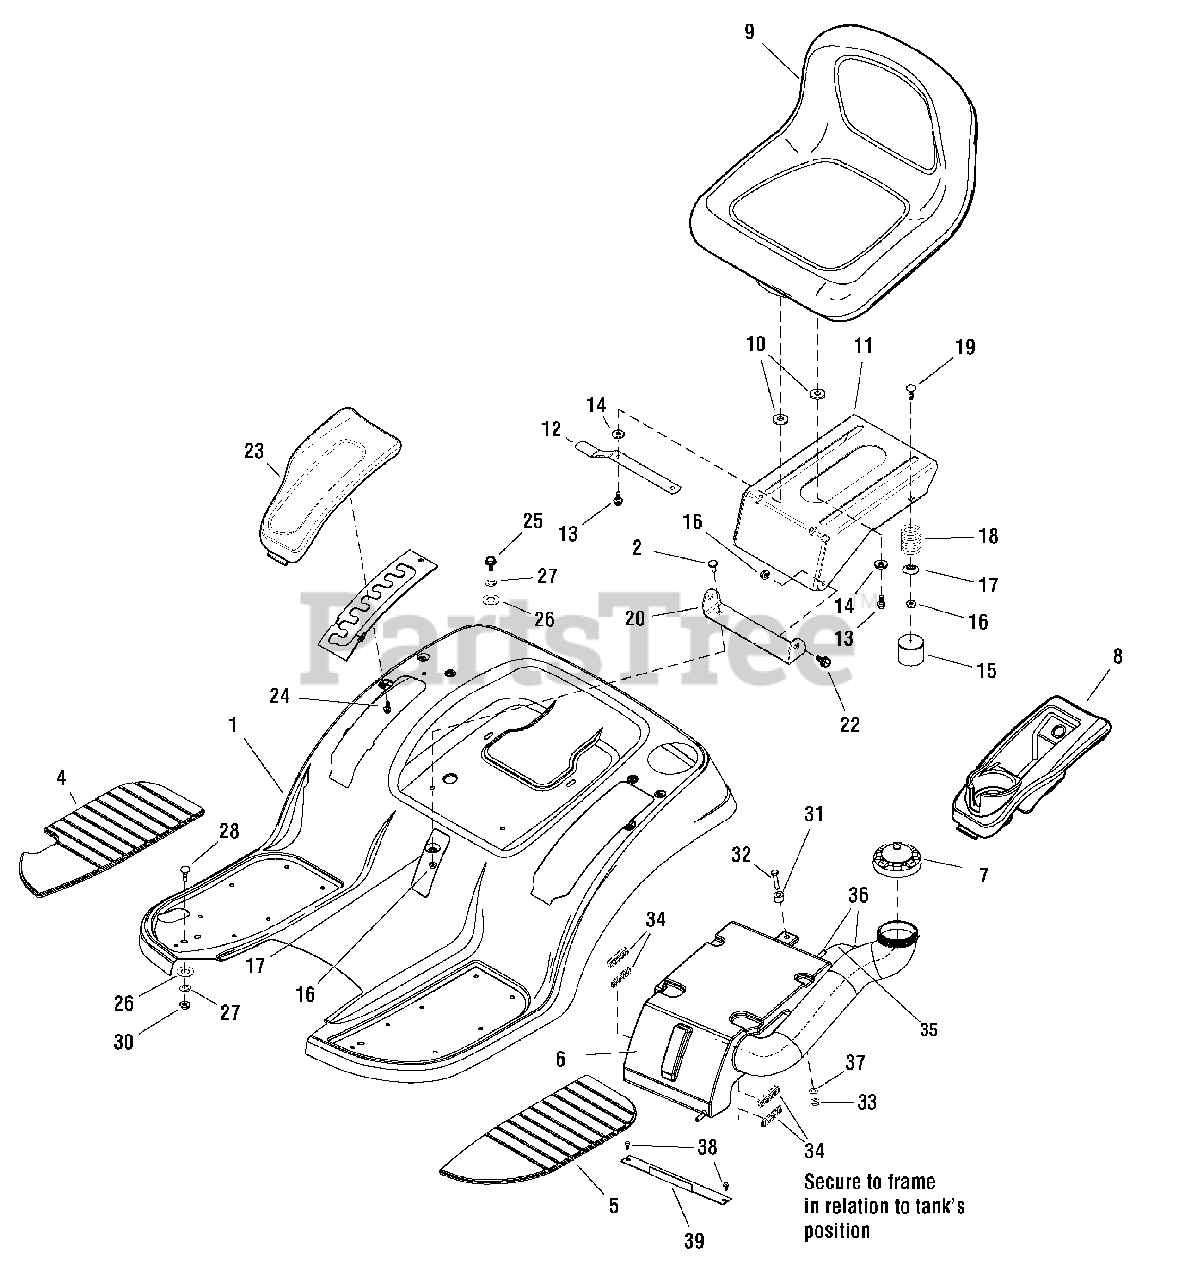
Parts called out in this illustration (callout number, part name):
1	DECK, Seat
2	BOLT, 5/16-18 x 3/4
4	PAD, Footrest, Right
5	PAD, Footrest, Left
6	TANK, Fuel 9-2770-244
7	CAP, Fuel
8	POD, Cup Holder, Left
9	SEAT, High Back
10	SPACER
11	SUPPORT, Seat
12	LATCH, Seat
13	SCREW, Flange 5/16-18 x 1
14	WASHER, 5/16
15	COVER, Spring
16	NUT, Hex Flange 5/16-18
17	WASHER, Spring
18	SPRING, Compression
19	BOLT, Round Head, 5/16-18 x 3/4
20	PIVOT, Seat
22	BOLT, Shoulder, 5/16-18 x 1/8
23	POD, Lift, Right
24	SCREW, Hex, 1/4-1/2
25	BOLT, M8 x 16
26	WASHER, 8.4
27	WASHER, 8
28	BOLT, M8 x 20
30	NUT, M8
31	DISTANCE, Lift 0-9521-289
32	BOLT, M6 x 30
33	NUT, M6
34	BRAID, Steel Insert 0-9634-219
35	HOSE, Air Escape 1-9920-248
36	CLIP, UM 5008
37	WASHER, 6.6
38	SCREW, Self Tap, 5-1/2 x 19
39	HOLDER, Tank
